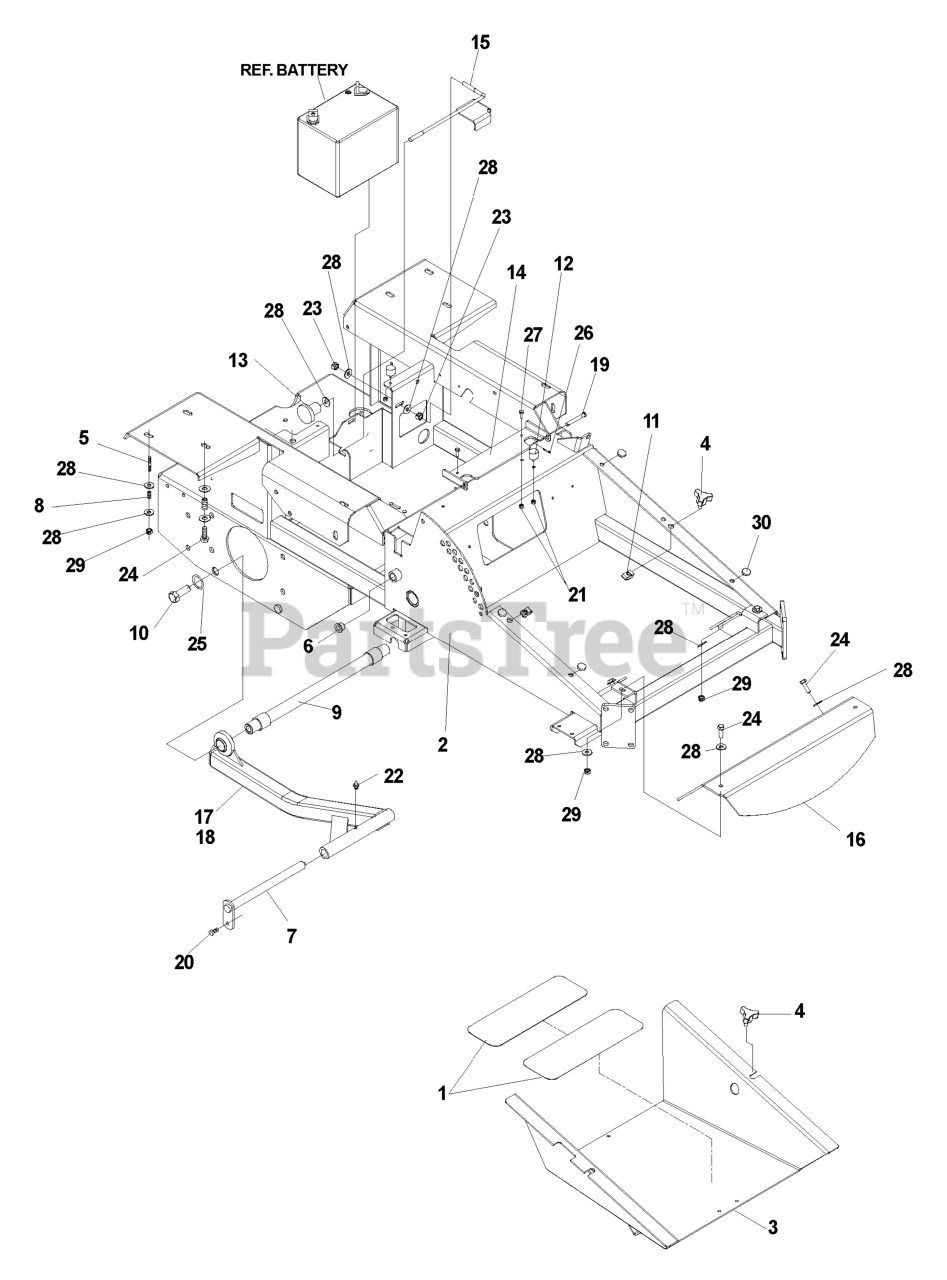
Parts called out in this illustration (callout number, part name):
1	ANTI-SKID PAD
2	IZ FRAME W/DECALS
3	IZ FOOTPLATE W/DECAL
4	KNOB W/STUD
5	STUD, 5/16C
9	STRUT MOUNT WELDMENT
10	HCS 5/8C X 2 GR.5
11	U-CLIP 5/16-18 NUT RETAINER
12	STUD/PLATE MOUNT
14	SEAT BRKT W/DECAL
15	BATTERY HOLD DOWN
16	FOOTREST ORANGE
19	CLEVIS PIN 3/8
20	HCS 5/16C X 3/4
21	NUT.1/4-20.HEX.NYLOC.ZD
22	ZERK
23	NUT 5/16C CENTERLOCK
24	HCS 5/16C X 1
25	LOCKWASHER 5/8
26	RP_COTTER PIN 1/8 X 3/4
27	HCS 1/4C X 3/4 HCS
28	WASHER 5/16 FLAT
29	NUT 5/16 NYLOC
30	GROMMET, BUMPER
